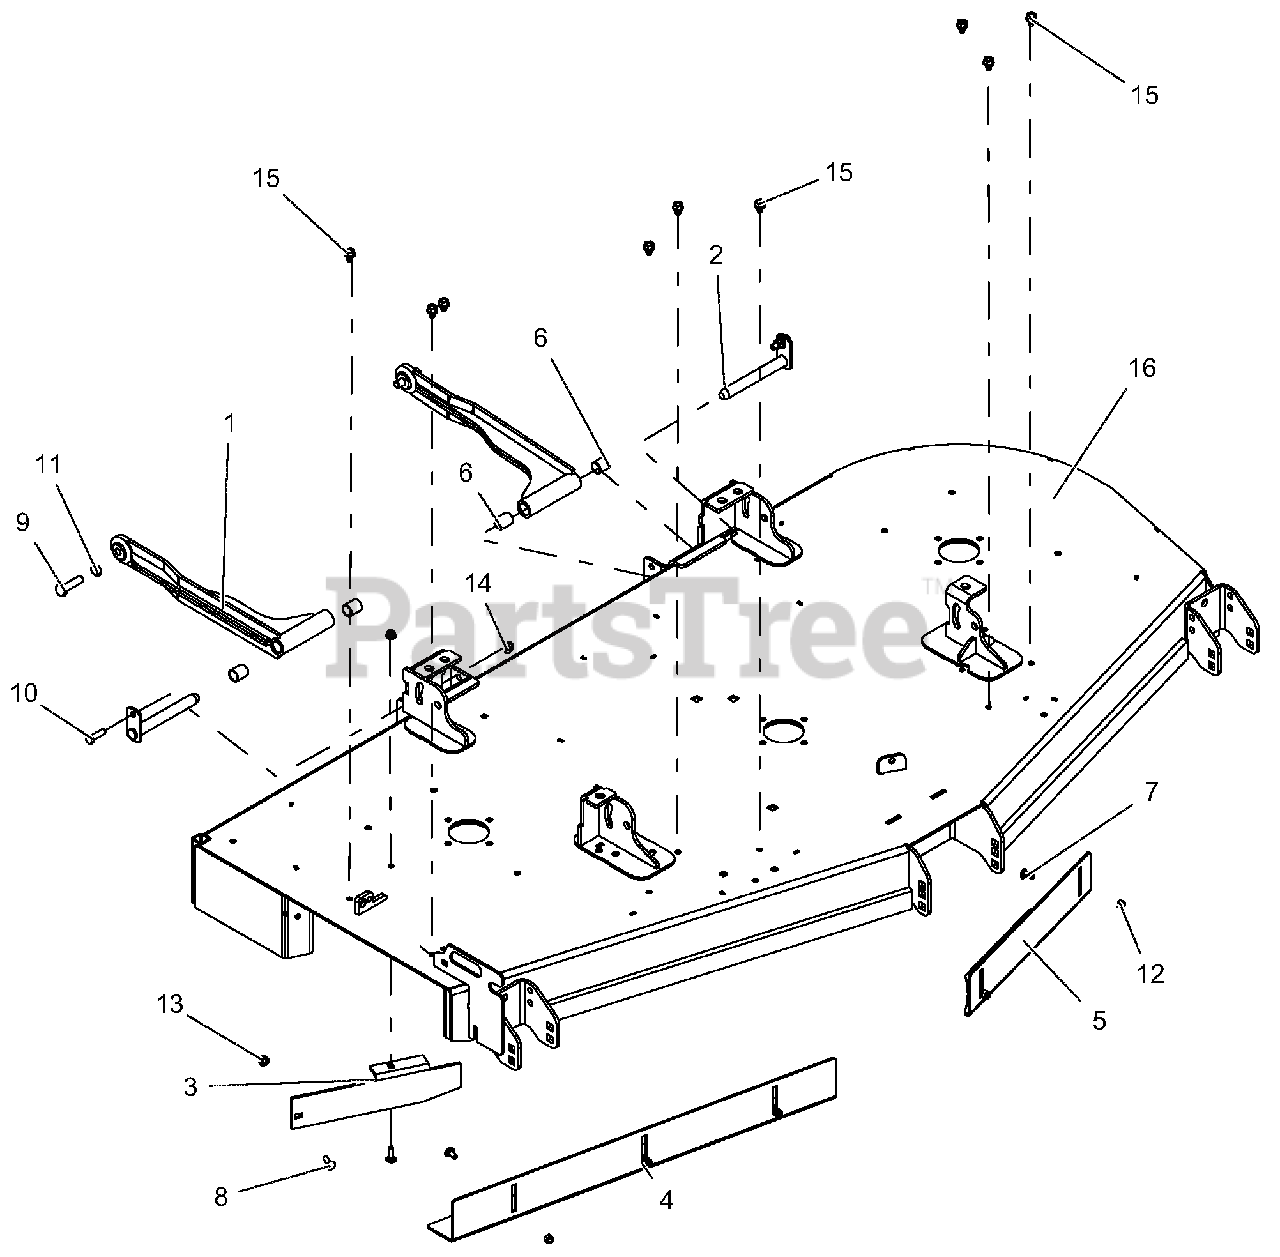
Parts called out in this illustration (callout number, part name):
1	DECK STABILIZER ARM W/BUSHINGS
2	WLDMT, MOWER MTG. PIN
3	BAFFLE, 72" DISCHARGE-RED
4	BAFFLE, 72" RH VACUUM-BLACK
5	BAFFLE, 72" LH VACUUM-BLACK
6	BRG, .75 X .875 X 1.00
7	@BLT-RDHDSQNK .31-18X.75 G5 YWZC
8	@BLT-RDHDSQSHNK .31-18X1.00 G5 Y
9	BLT-HEX .50-13X1.75 GR5 YWZC EP80
10	BLT-HEX .38-16X1.25 GR5 YWZC
11	@WSHR-LK .50X.125 REG YWZC
12	@NUT-LK-NYL .312-18 YWZC
13	NUT-LK-NYL-FLG .31-18 YWZC
14	NUT-LK-NYL-FLG .38-16 YWZC
15	SCR-TAP .38-16X.50 HWH TR YWZ
16	72" SIDE DISCH DECK W/SAFETY DECALS
